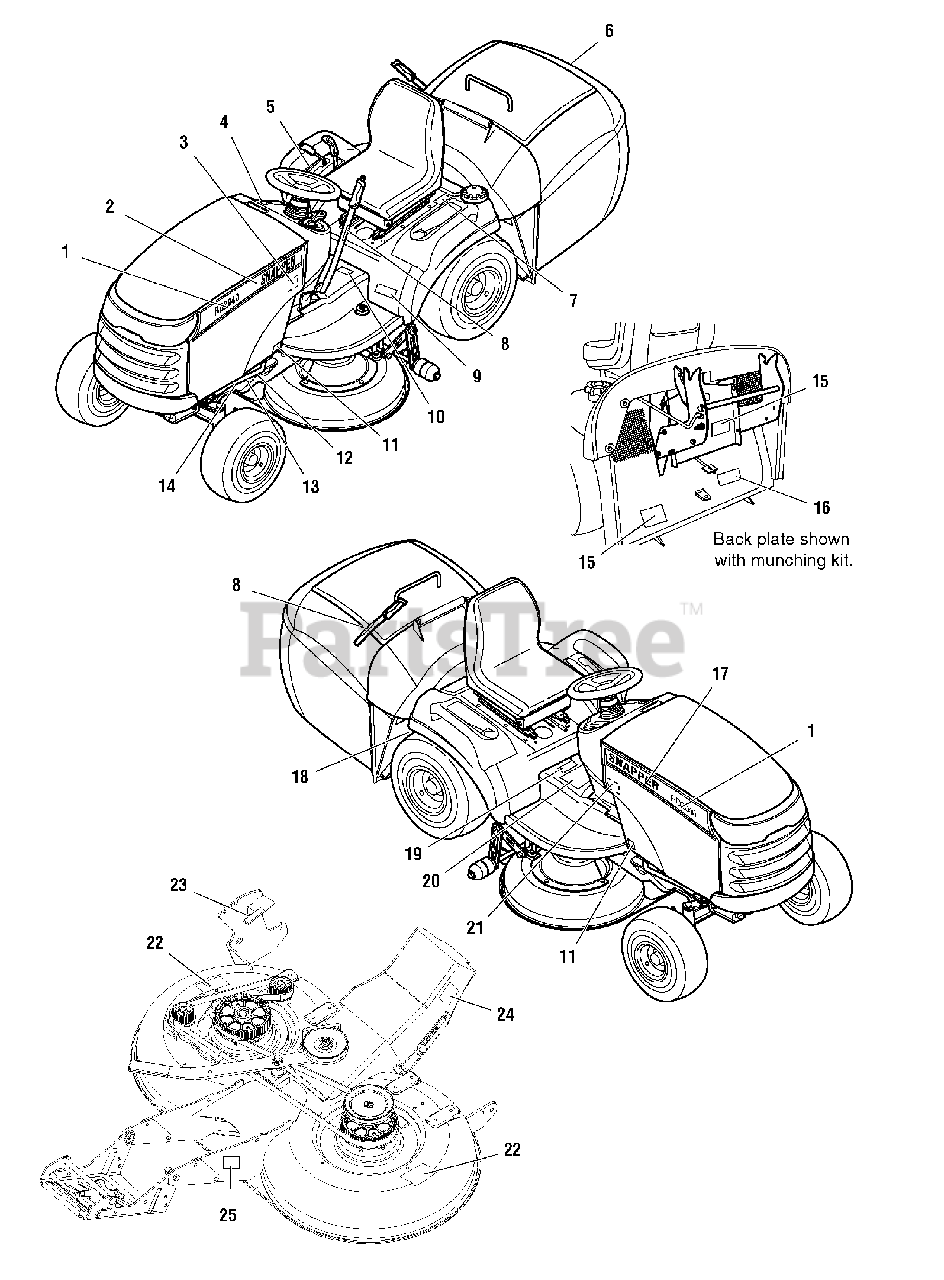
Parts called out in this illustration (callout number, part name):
1	DECAL, RD1740
1	DECAL, RD1840
1	DECAL, RD2040
2	DECAL, Hood Stripe, Snapper, LH
3	DECAL, Belt & Blade
4	DECAL, Ignition Switch
5	DECAL, Crusie / Lift
6	DECAL, Snapper
7	DECAL, Latch Release
8	DECAL, Hopper Lever
9	DECAL, Latch Release
10	DECAL, Hopper Pedal
11	DECAL, Protective, Clear
15	DECAL, Danger Operating W/O Catcher
16	DECAL, Drawbar Max Load
17	DECAL, Hood Stripe, Snapper, RH
18	DECAL, Transmission Release Valve
19	DECAL, Danger Catcher Open
20	DECAL, Warning/Danger Icons, Tunnel
21	DECAL, Touch Up Paint
22	DECAL, Danger Rotating Blades
22	DECAL, Danger Rotating Blade, Export Only
23	DECAL, Height Of Cut
24	DECAL, Danger, Discharge Tube
